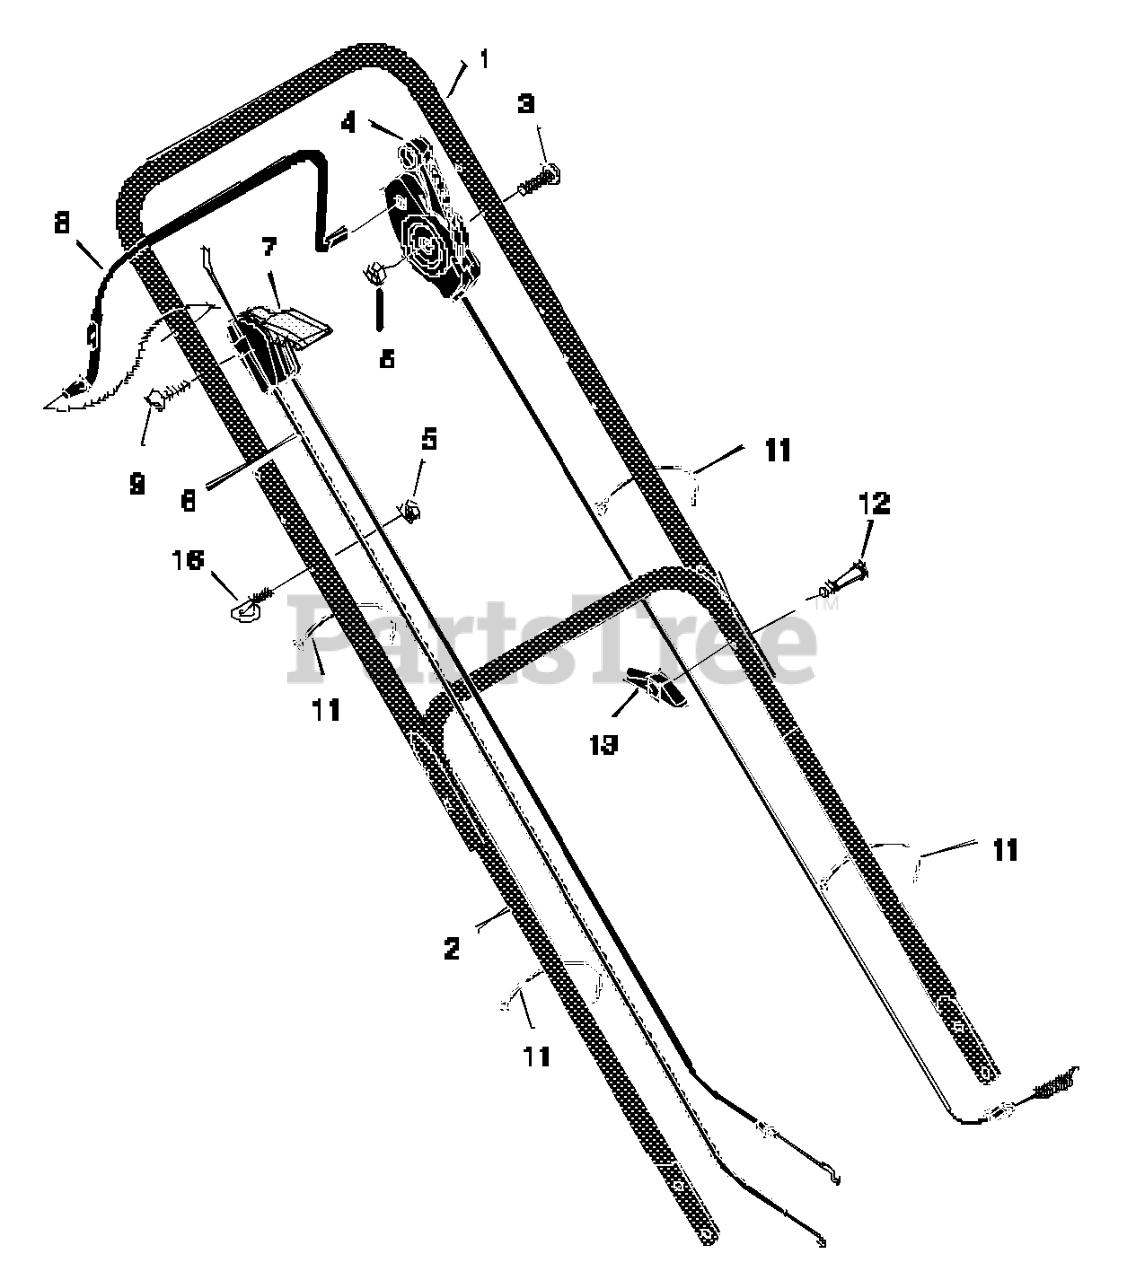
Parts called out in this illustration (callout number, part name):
1	Handle, Upper (Black)
2	Handle, Lower (Black)
4	Control, Drive
5	Locknut
6	Cable, Stop
7	Throttle Control
8	Lever, Stop
11	Fastener, Cable
13	Knob
16	GUIDE, ROPE
